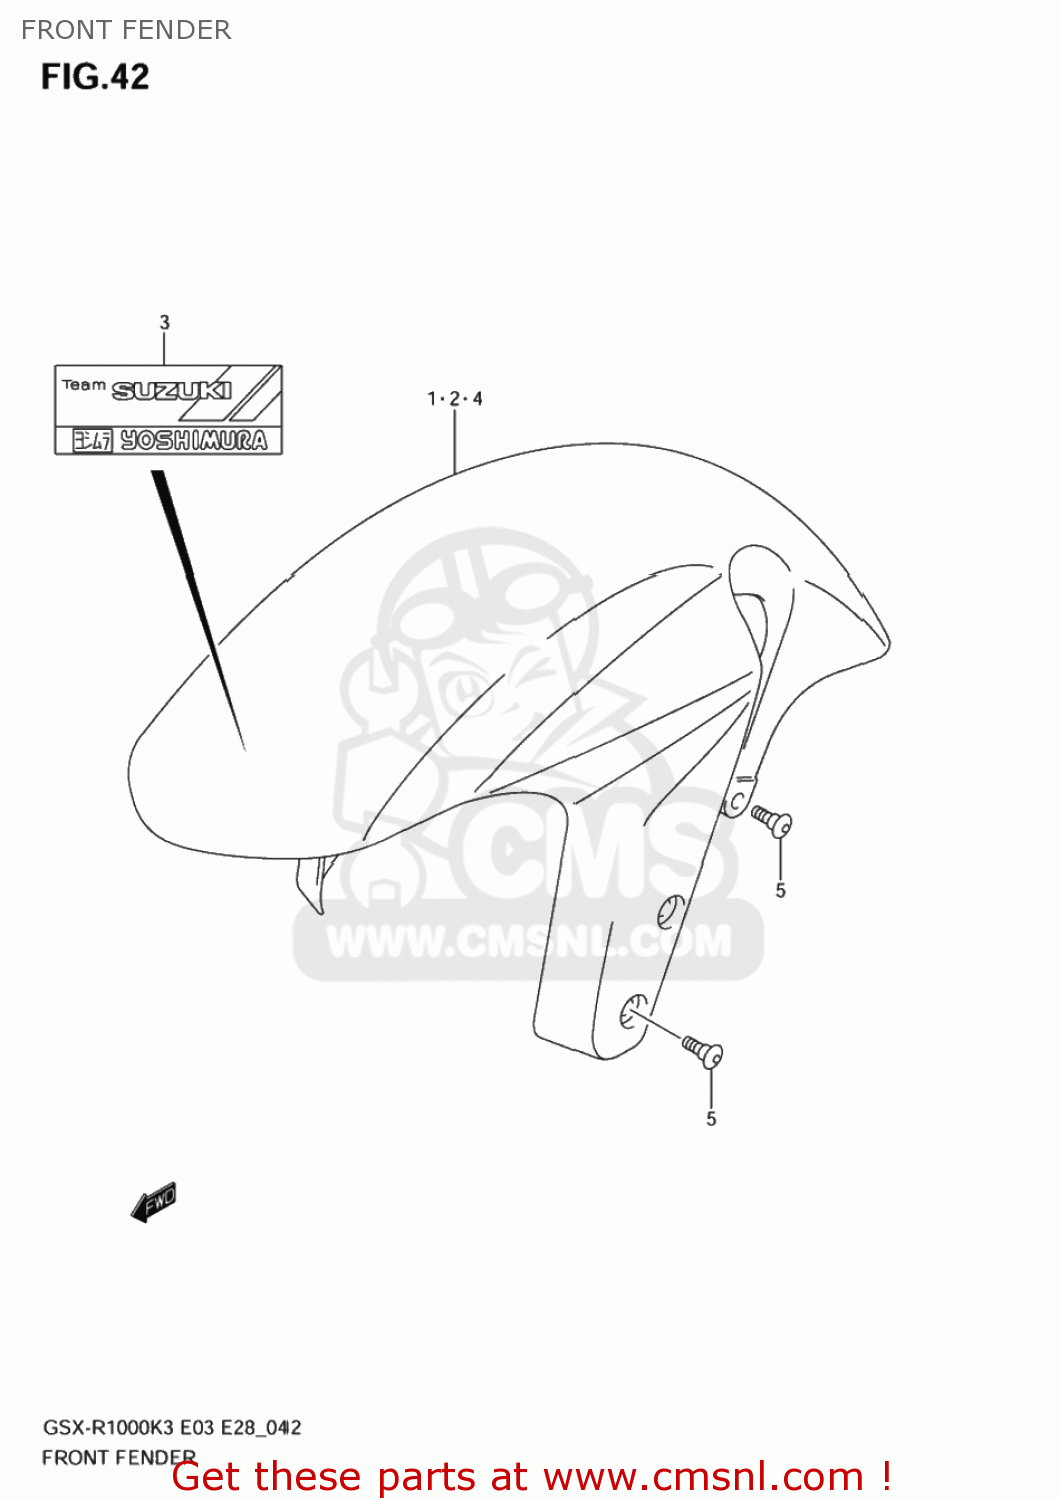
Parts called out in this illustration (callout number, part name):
1	FENDER,FR
2	FENDER ASSY,FR(BLACK)
3	EMBLEM,TEAM-SUZUKI
4	FENDER,FR
5	SCREW(6X16)
